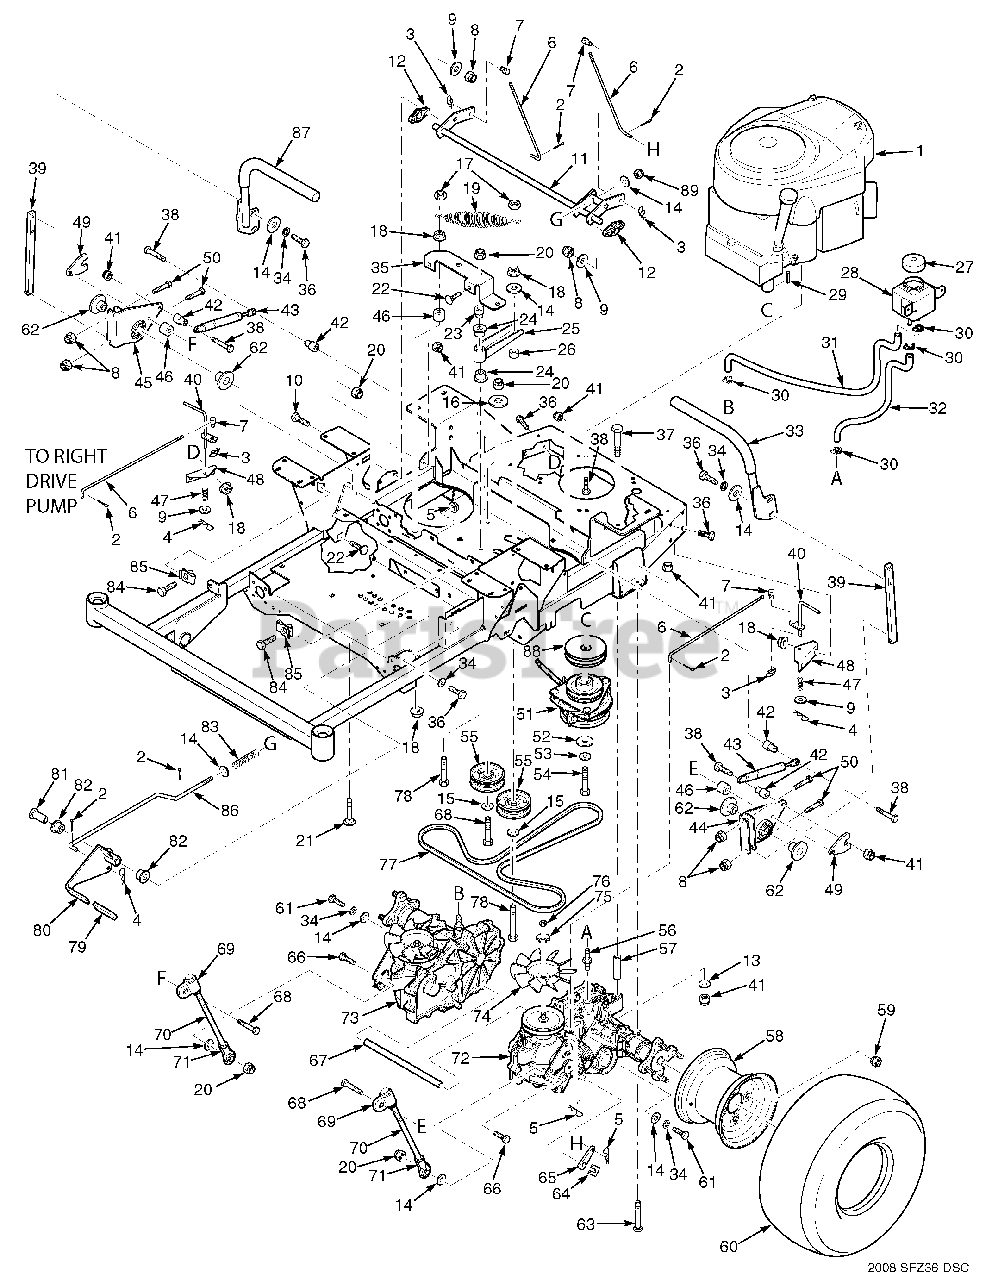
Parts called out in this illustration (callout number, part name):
1	Engine, Briggs & Stratton 20hp
2	Cotter Pin, 3/32 x 1"
3	Pin, Rue Cotter 3/8" Dia.
4	Hair Pin, .080 x 1.19"
5	Nut, Serrated Flange 5/16-18
6	Rod, Brake Adjustment
7	Joint, Swivel
8	Nut, Elastic Stop 1/4-20
9	Flatwasher, 1/4-.312 x .750 x .065
10	Bolt, Serrated Flange 1/4-20 x 1-1/4"
11	Weldment, Brake Lever
12	Bearing
13	Flatwasher, 5/16-.375 x .875 x .083
14	Flatwasher, 3/8-.391 x .938 x .105
15	Flatwasher, 3/8-.391 x .938 x .105 HD
16	Flatwasher, 3/8-.406 x 1.5 x 7 GA.
17	Nut, Center Lock 3/8-16
18	Nut, Serrated Flange 3/8-16
19	Spring, Transmission Idler
20	Nut, Elastic Stop 3/8-16
21	Bolt, Carriage 3/8-16 x 2"
22	Bolt, Carriage 5/16-18 x 3/4"
23	Shaft Pivot, Idler Arm
24	Bearing
25	Transmission Idler Arm Assembly
26	Spacer, Idler Pulley
28	Reservoir Assembly
29	Key, 1/4 x 1/4 x 1-3/4"
30	Clamp, 0.87" Max Dia.
31	Hose, RH Transmission
32	Hose, LH Transmission
33	Handle Bar Assembly, w/Grip
34	Lockwasher, 3/8" Spring
35	Support, Idler Arm
36	Bolt, Hex Head 3/8-16 x 1"
37	Bolt, Hex Head 5/16-18 x 6"
38	Bolt, Hex Head 5/16-18 x 1-1/2"
39	Bar, Control Lever
40	Dump Valve Lever
41	Nut, Elastic Stop 5/16-18
42	Spacer, Pump Dampener
43	Dampener
44	Control Link, LH
45	Control Link, RH
46	Spacer
47	Spring
48	Bracket, Dump Mounting
49	Nut, Control Linkage
50	Bolt, Hex Head 1/4-20 x 1-1/2"
51	Electric Clutch Assembly
52	Flatwasher, 7/16-.469 x 1.75 x .25
53	Lockwasher, 7/16" spring
54	Bolt, Hex Head 7/16-20 x 2-1/4" Patch
55	Pulley, 3-1/2" Dia.
56	Fitting, Transmission
57	Spacer, Axle
58	Rim w/Valve Stem
59	Wheel Nut, 1/2-20
60	Wheel Assembly
61	Bolt, Hex Head 3/8-16 x 2-1/4"
62	Spacer, Linkage
63	Bolt, Hex Head 5/16-18 x 2-1/4"
64	Clip, Brake Lever
65	Lever, Brake
66	Bolt, Hex Head 3/8-16 x 1-1/4"
67	Spacer, Axle
68	Bolt, Hex Head 3/8-16 x 2"
69	Rod End, Adjustable
70	Linkage, Pump
71	Stake, Rod End Assembly
72	Transaxle Assy., (ZJ-KMEF-3LKG-1FXX)
73	Transaxle Assy., (ZJ-GMEF-3LKF-1FXX)
74	Fan (order through Hydro-Gear)
75	Fan Washer
76	Fan Nut
77	Belt, Transmission Drive
78	Bolt, Hex Head 3/8-16 x 3"
79	Grip, Brake Handle
80	Brake Handle Assembly
81	Spacer, Brake Handle
82	Bearing
83	Spring, Brake
84	Bolt, Hex Head 3/8-16 x 1-1/4" Special Lock
85	U-Nut, 3/8-16
86	Rod, Brake Linkage
87	Handle Bar w/Grip
88	Pulley, 4-1/2" Dia. 1" Bore
89	Nut, Elastic Stop 3/8-24 Gr. 8
